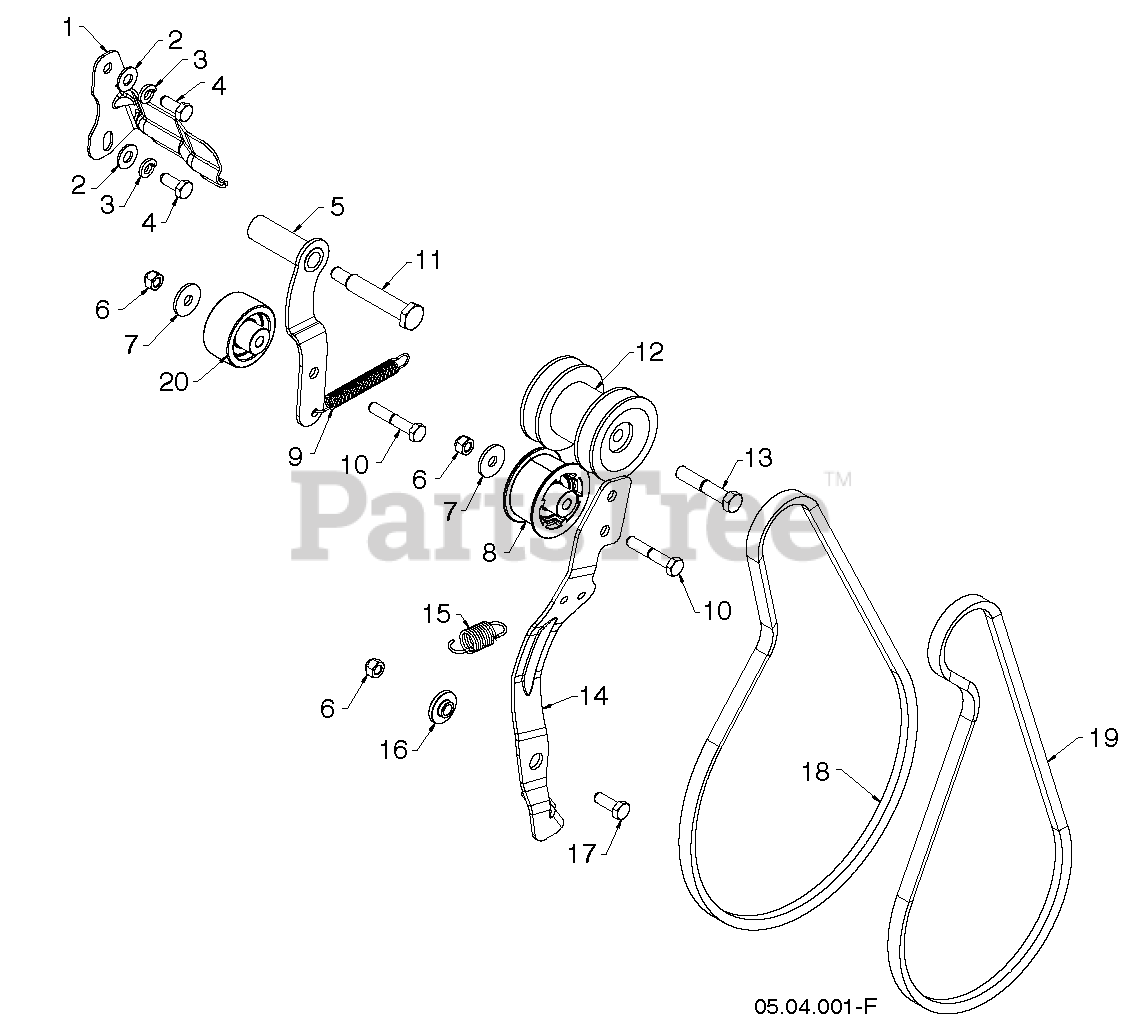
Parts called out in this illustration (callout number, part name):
1	BRACKET.BELT.KEEPER.004.BZP
2	WASHER M
3	WASHER.LOCK.HVY.HLCL.SPR.5/16
4	SCREW 5/16-24 X .75 GR5
5	ARM.IDLER.WELDMENT.DRIVE.008
6	NUT.71038.31-18.HEX.NYLOCK
7	STEEL WASHER
8	PULLEY,IDLER,2.00 W SPA
9	SPRING RETURN IDLER ARM
10	BOLT, HEX 5/16-18X1-3/4
11	BOLT 5/16-24X2.25 HEX HEAD SHO
12	RP PULLEY.ASM.IMPELLER/DRIVE
13	BOLT.BLADE
14	BRACKET ARM.IDLER.IMPELLER ARM
15	SPRING RETURN, IDLER ARM, IMPE
16	RP BUSHING, IDLER PIVOT
17	BOLT
18	RP.BELT.DRIVE.4LX38.2
19	BELT IMPELLER_4L X 35.4
20	PULLEY.IDLER.FLANG.2.O/SPACER
